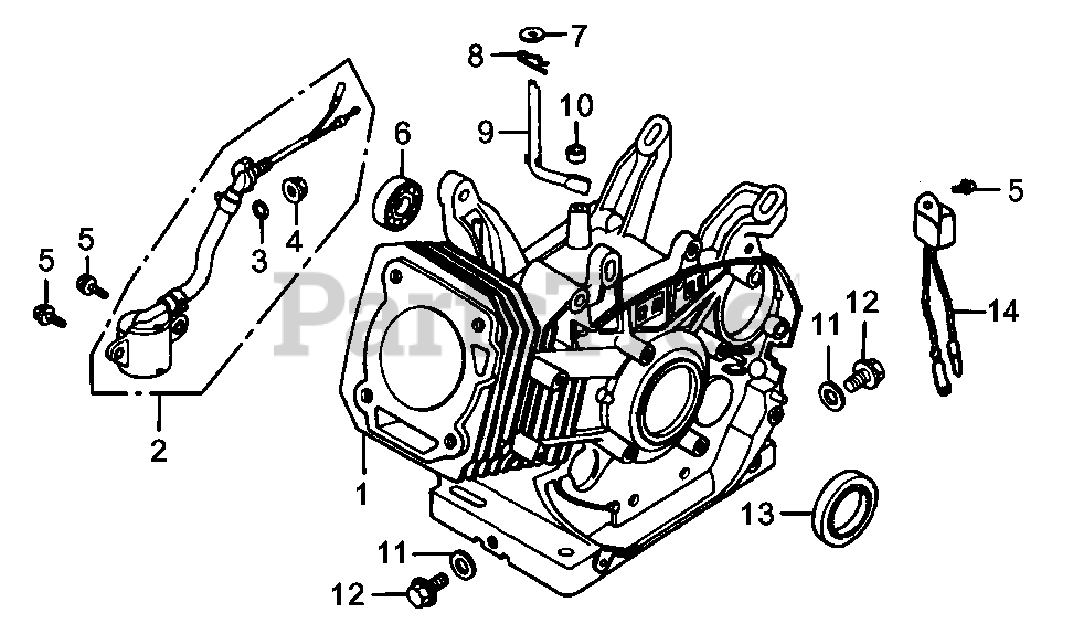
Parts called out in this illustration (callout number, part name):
1	CRANKCASE
2	SWITCH ASSY., OIL LEVEL
3	O-RING FOR OIL SWITCH
4	NUT, FLANGE
5	BOLT, FLANGE
6	BEARING, RADIAL BALL 6202
7	WASHER, PLAIN 8 x 16 x 1.2
8	PIN, LOCK
9	SHAFT, GOVERNOR ARM
10	SEAL, OIL 8 x 14 x 4
11	WASHER, DRAIN PLUG 12 x 20 x 2
12	BOLT, DRAIN PLUG M12 x 1.5 x 15
13	SEAL, OIL 35 x 52 x 7
14	ALERT UNIT, OIL
